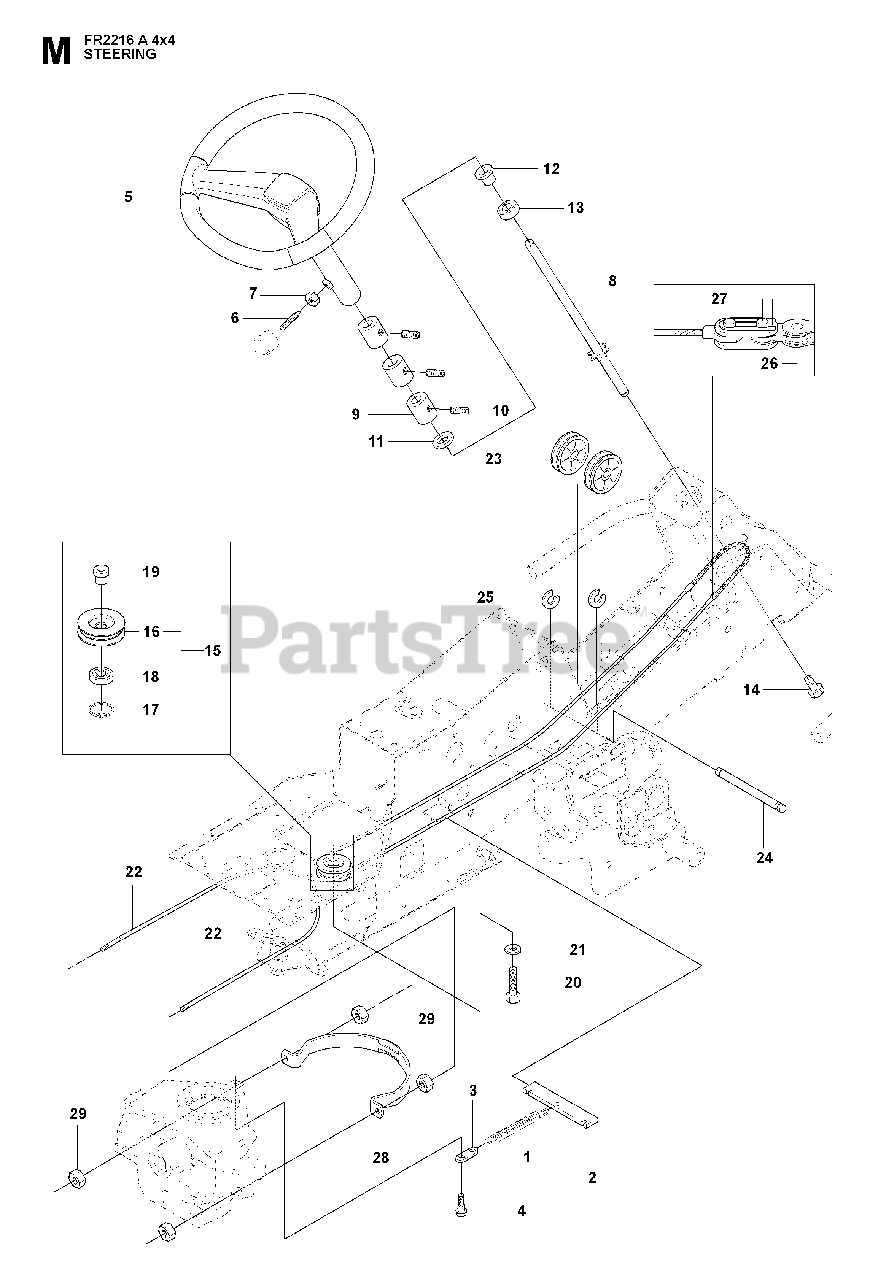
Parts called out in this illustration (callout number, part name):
2	SPRING BRACKET
3	CONNECTOR
5	STEERING WHEEL
7	NUT
8	ROD STEERING ASSY
13	BALL BEARING 6004-2RS1
17	CIRCLIP SGH 47
18	BALL-BEARING 6204-2RS
20	COLLAR SCREW
22	RP STEERING CABLE COMPLETE
25	RETAINING RING
26	STEERING CHAIN
28	WIRE GUIDE
